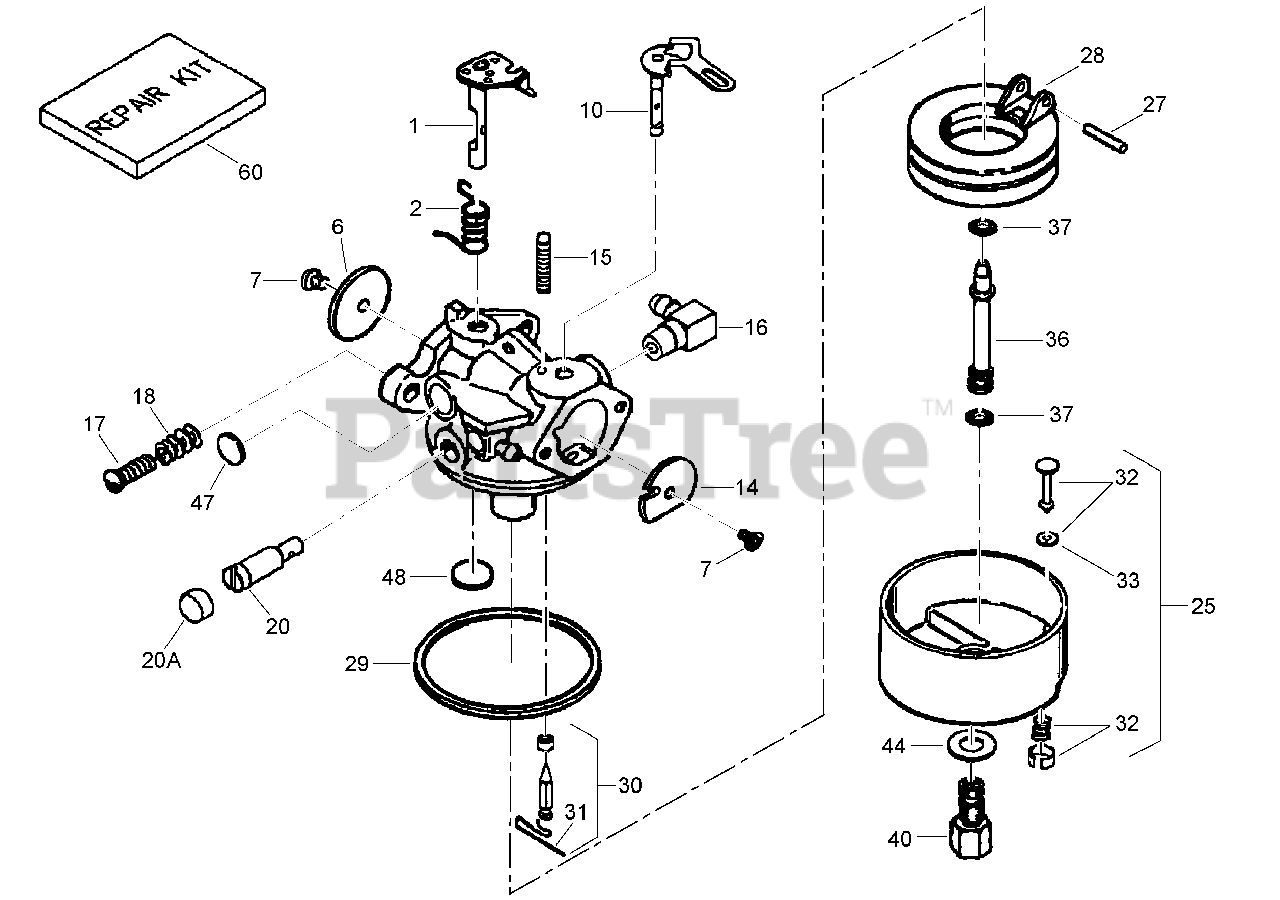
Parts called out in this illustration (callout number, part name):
1	Throttle Shaft and Lever ASM
2	Spring-Return, Throttle
6	Shutter-Throttle
7	Screw-Shutter
10	Choke Shaft and Lever Asm
14	Shutter-Choke
15	Spring-Positioning, Choke
16	Fitting-Inlet, Fuel
17	Screw-Throttle Crack and Idle Speed
18	Spring-Tension
20	Screw-Restrictor, Idle
20A	Cap-Screw, Idle Restrictor
25	Bowl-Float (no drain) (after 1/01/2006)
25	Float Bowl Asm (before 1/01/2006) (Includes 32-33)
27	Shaft-Float
28	Float (Plastic)
29	O Ring-Bowl, Float
30	Inlet Needle, Seat and Clip ASM (Includes 31)
31	Clip-Spring
32	Bowl Drain ASM (before 1/01/2006)
33	Gasket-Plunger, Drain (before 1/01/2006)
36	Tube-Nozzle, Main
37	O-Ring
40	Nut-Bowl, High Speed
44	Washer-Nut, Bowl
47	Plug-Welch, Idle Mixture Well
48	Plug-Welch, Atmospheric Vent
60	Carburetor Repair Kit
